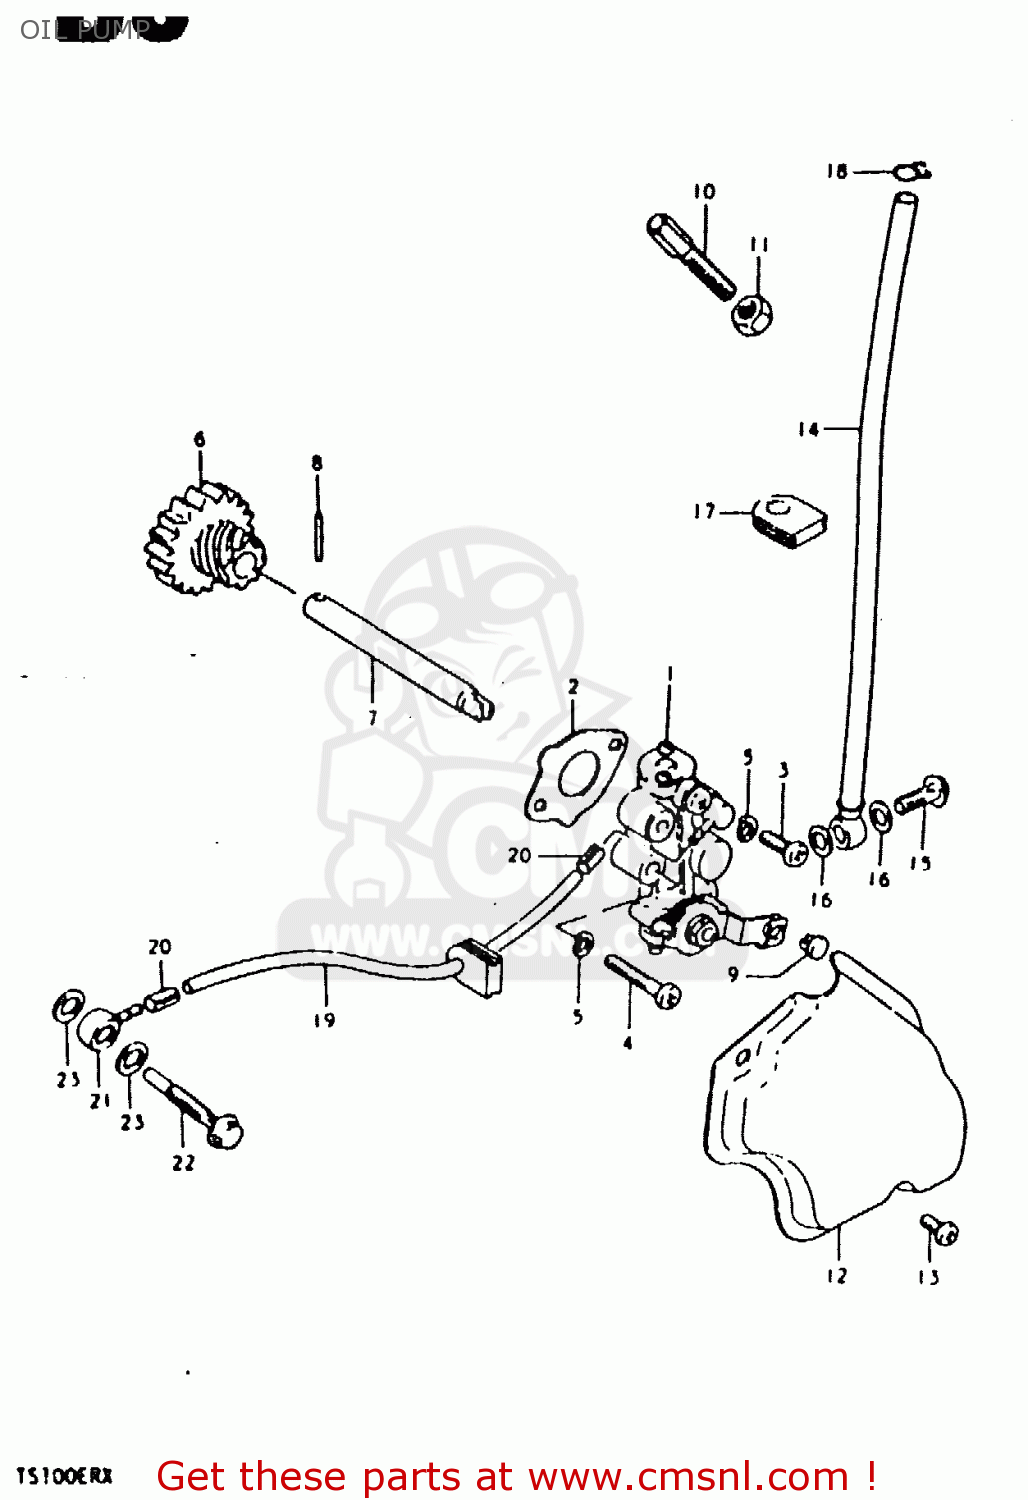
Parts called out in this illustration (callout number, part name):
1	PUMP ASSEMBLY,OIL
2	GASKET,OIL PUMP (NAS)
3	SCREW
4	SCREW
5	LOCK WASHER
6	GEAR,OIL PUMP DRIVE
7	SHAFT,OIL PUMP DRIVE
8	PIN(2.5X19.8)
9	TERMINAL,CABLE
10	BOLT
11	NUT
12	CAP,OIL PUMP INSPECTION
13	SCREW
14	HOSE,OIL NO.1
15	UNION BOLT
16	GASKET(6.2X11X1).2 (NAS)
17	GROMMET
18	CLIP
19	HOSE,OIL NO.2
20	CLIP
21	UNION
22	UNION
23	GASKET(6.2X11X1).2 (NAS)
